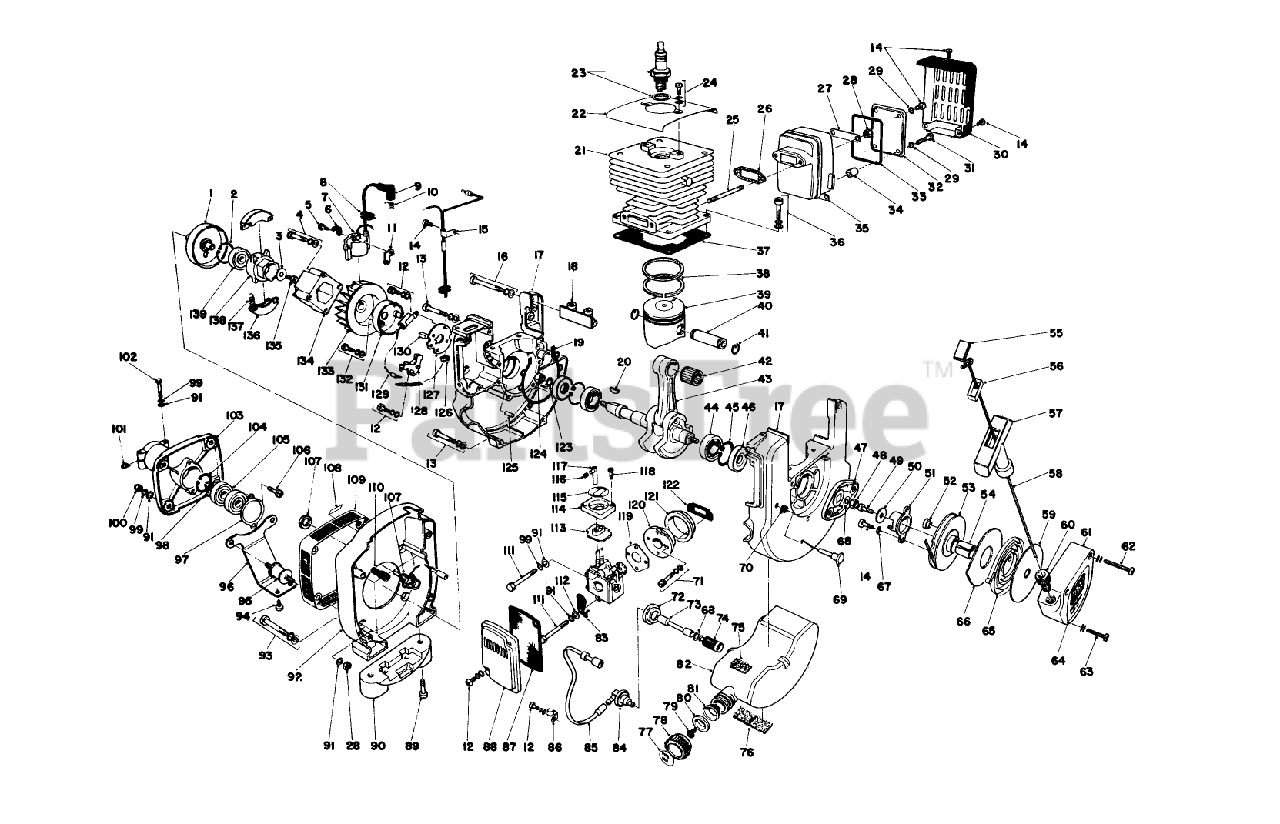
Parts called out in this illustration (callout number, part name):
53	RECOIL DRUM
80	CHECK VALVE HOLDER
128	CONTACT POINT
129	CONDENSER
